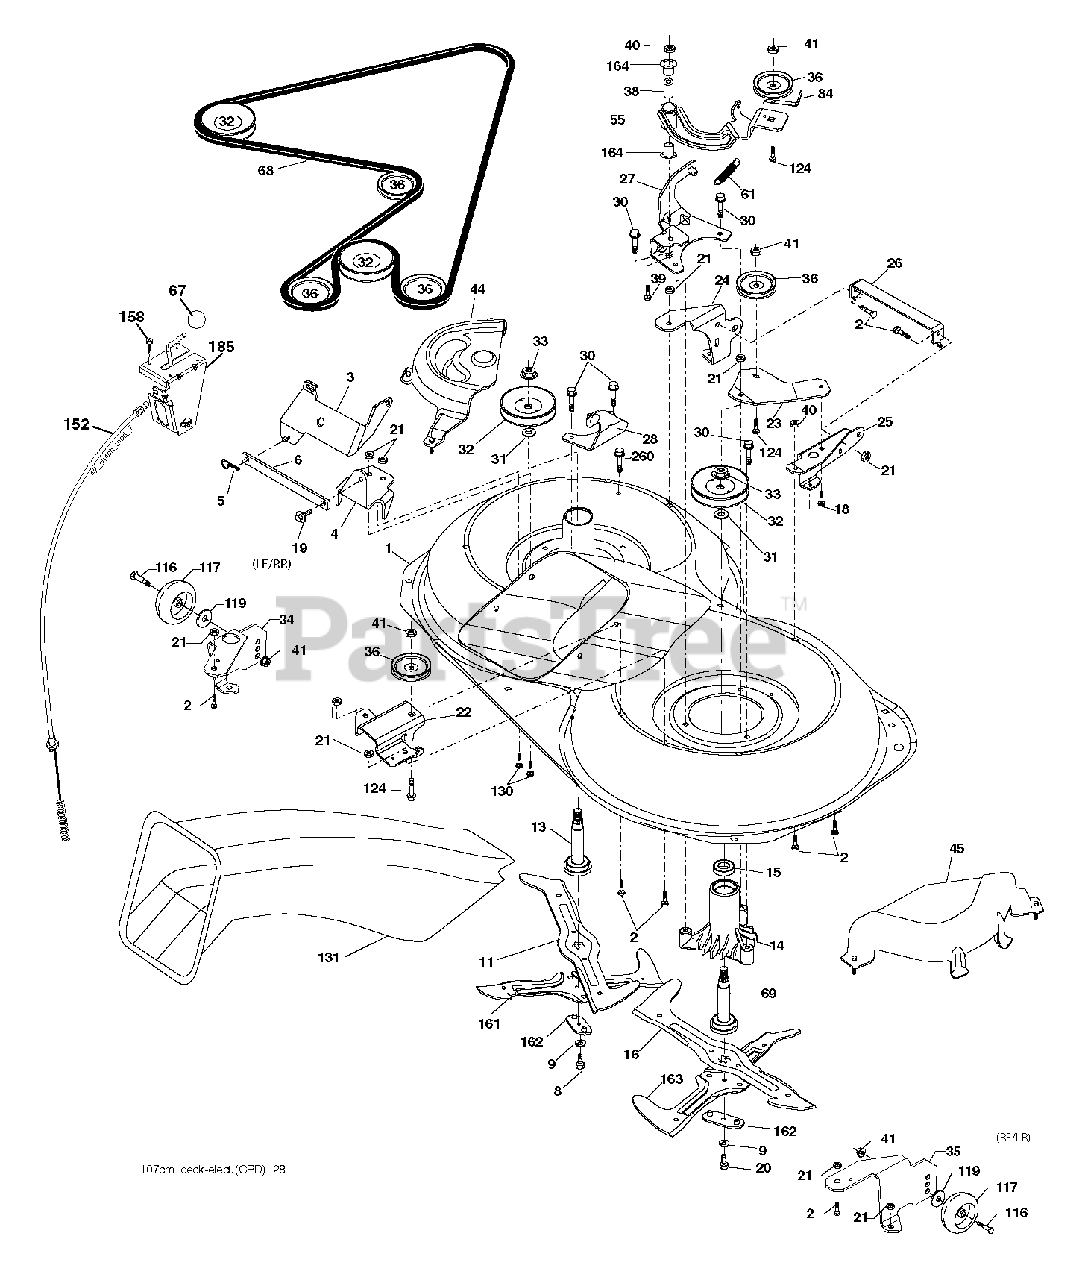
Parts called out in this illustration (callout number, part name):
2	BOLT
3	BRACKET
5	RETAINER-SPRNG RB
6	BAR SWAY
8	Bolt, 3/8-24 X 1.25 Gr8
9	LOCKWASHER
11	BLADE.3N1.LH.CRD
13	SHAFT ASM VENT
16	BLADE.3N1.RH.CRD
19	BOLT SHD 5/16-18
20	BOLT.3/8-24X1.25GR8. LHTHRD
21	LOCKNUT
22	BRACKET
23	BRACKET
27	BRACKET
30	SCREW, WASHER HEAD
31	WASHER.SPACER.MANDREL
33	NUT.FLANGE.LOCK.TOP
36	PULLEY.IDLER.4.25
40	LOCKNUT
41	NUT LOCK FLG 3/8-16 UNC
45	MANDREL COVER
46	SCREW.1/4-20X5/8
67	KNOB T (3/8 HOLE)
68	HEX-BELT 107 MOWER
69	SHAFT.ASM.W/LWR.BRG.RH.THREAD
84	KEEPER, BELT IDLER
116	BOLT.SHOULDER.3/8-16X3-5/8
117	WHEEL. GUAGE RALLY
124	BOLT.3/8-16X1.50
158	SCREW
164	BRNG T
185	HEAD ASM. CABLE CLUTCH
260	SCREW 3/8-16X1/2
